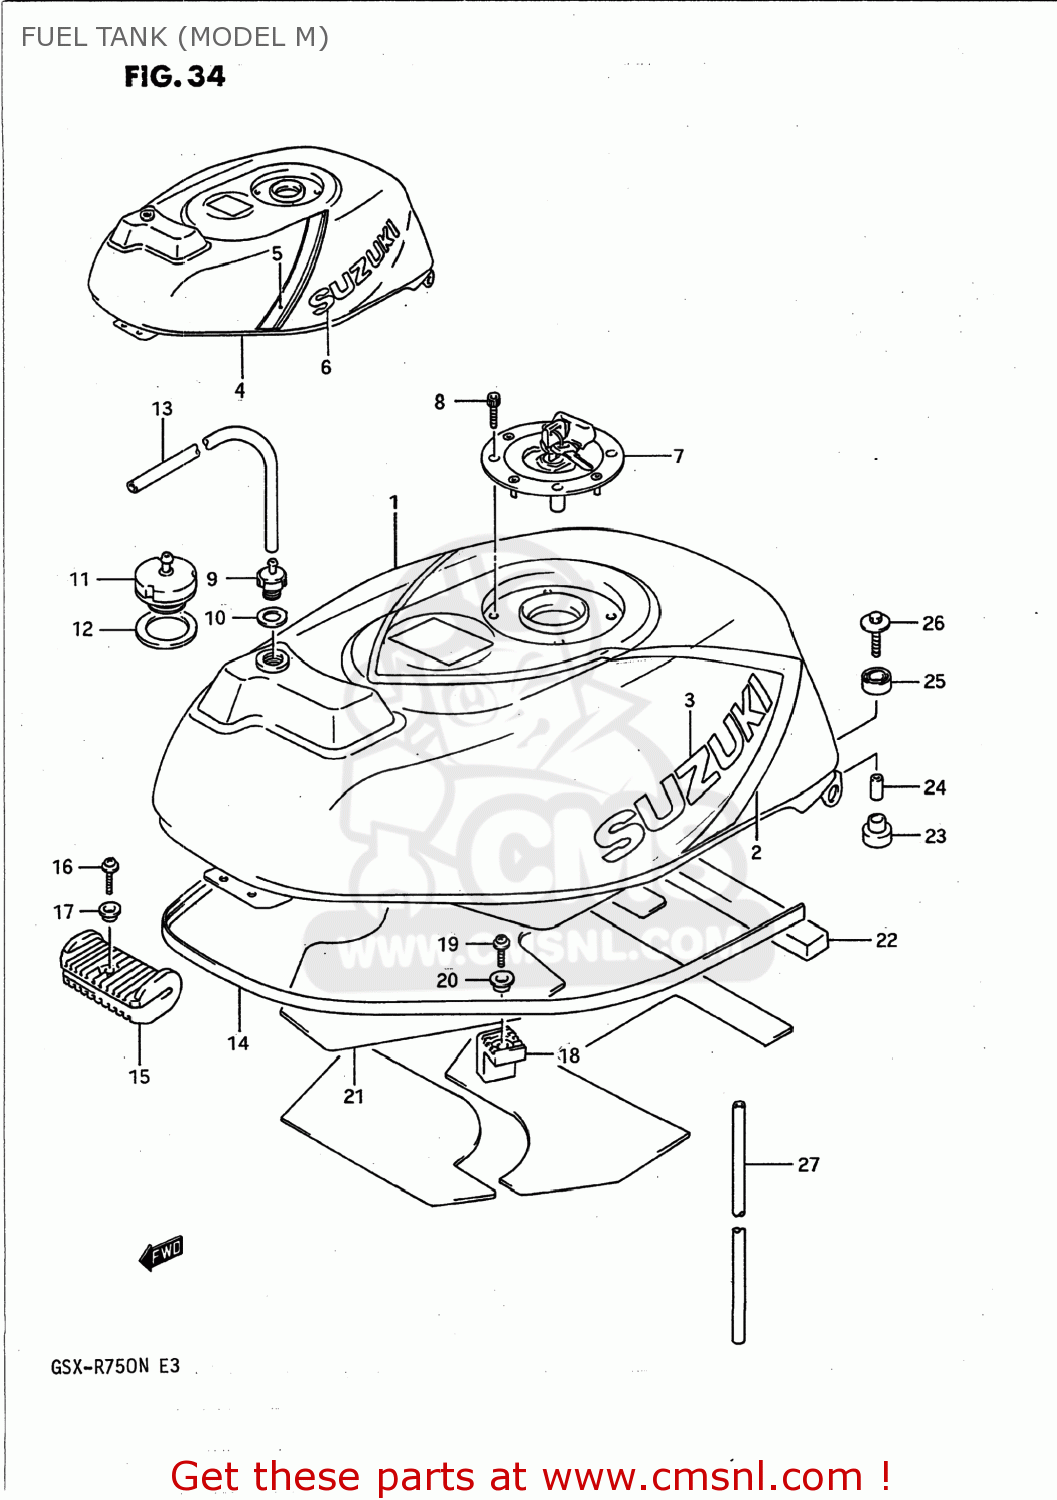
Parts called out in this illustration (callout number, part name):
1	TANK ASSEMBLY,FUEL
2	TAPE,FUEL TANK
3	EMBLEM,FUEL TANK(WHITE)
4	TANK ASSEMBLY,FUEL
5	TAPE SET,FUEL TANK
6	EMBLEM,FUEL TANK
7	CAP SET,FUEL TANK
8	BOLT(5X20)
9	PLUG,FUEL TANK BREATHER
10	GASKET(12.5X20X2.5) (NAS)
11	(CA) VALVE,FUEL TANK BREATHER
12	GASKET 27X40X2.5 (NAS)
13	HOSE(5X8.2X600)
14	MOLDING,FUEL TANK
15	CUSHION,FUEL TANK FR
16	SCREW 5X10
17	WASHER
18	CUSHION,FUEL TANK SIDE
19	SCREW
20	WASHER
21	SHIELD,FUEL TANK HEAT
22	CUSHION, AIR SEAL
23	CUSHION
24	SPACER
25	CUSHION
26	BOLT(6X35)
27	HOSE
